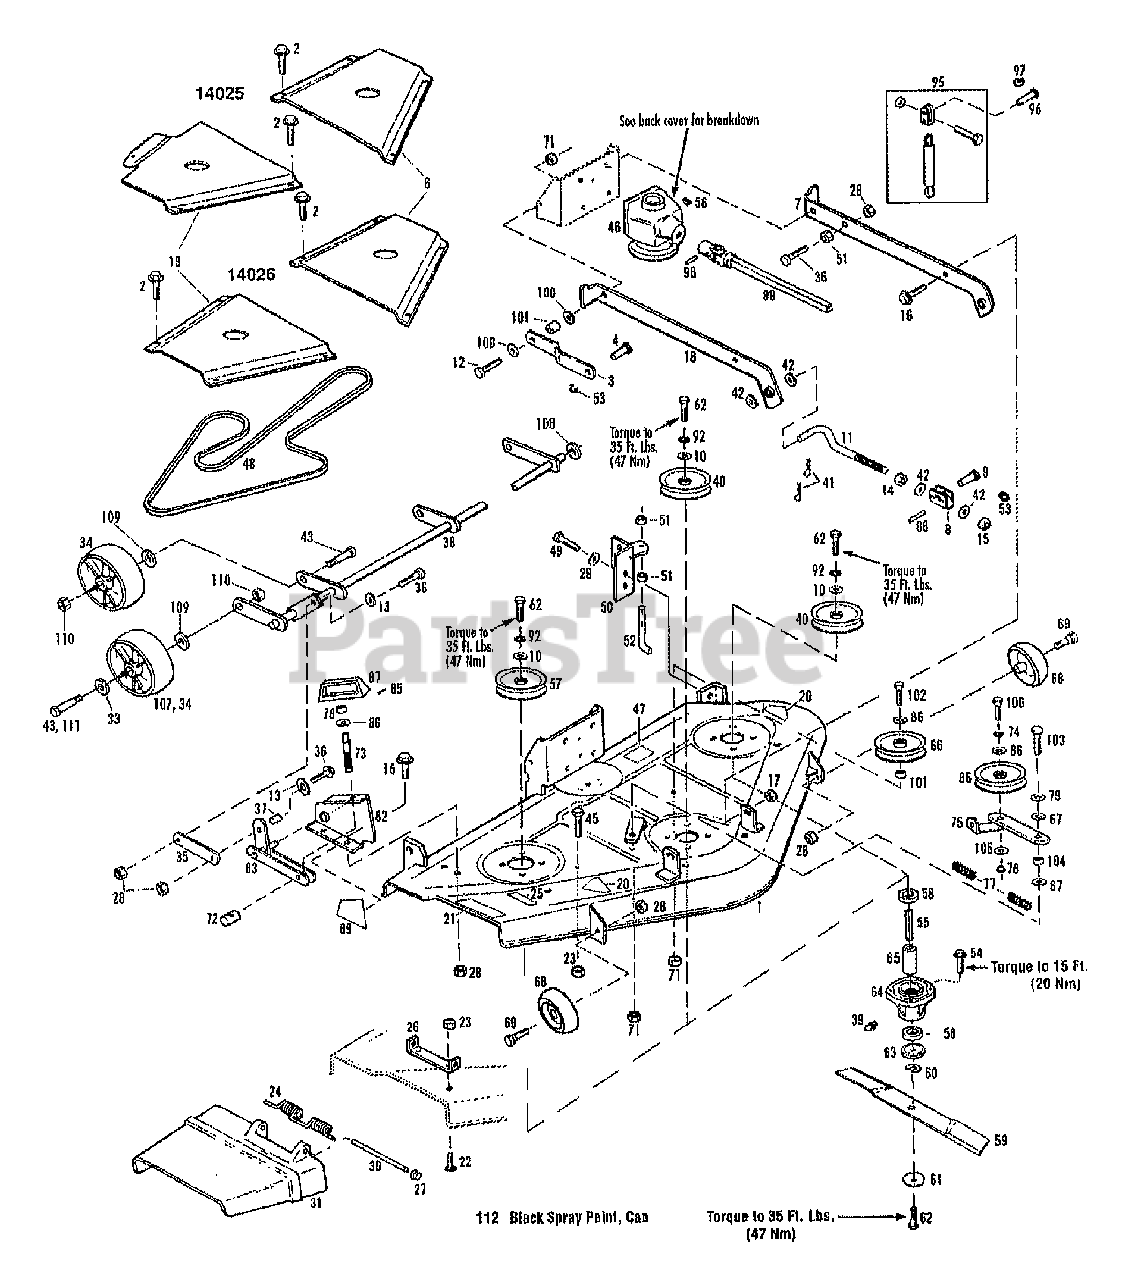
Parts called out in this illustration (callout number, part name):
1	BASE-MOWER 42" SD W/DECALS {14025}
1	BASE-MOWER 48" SD W/DECALS {14026}
2	SCR 1/4-20X.5 FL SELF TAP
3	LINK-DRAG
4	PIN-CLEVIS .625X1.44
6	COVER-BELT LH {14025}
6	COVER-BELT LH {14026}
7	SUPPORT-DECK LH
8	BRKT-HITCH
9	PIN-CLEVIS .62X2.50 ZP
10	WASHER-1.25X.5X.083 ZP
11	LINK-HITCH
12	SCR-HH 1/2-13X1.75 G5 ZP
13	WASHER-FLAT 3/8 SAE
14	NUT
15	NUT-H/LK 3/4-10
16	SCR-HFLK 3/8-16X1.00 ZP
17	NUT-HFLK 3/8-16 ZP
18	SUPPORT-DECK RH
19	COVER-BELT RH {14025}
19	COVER-BELT RH {14026}
20	DECAL-OPEI CAUTION
21	DECAL-DANGER
22	BOLT-CARR 5/16-18X.63 ZP
23	NUT-TOP/LK 5/16-18 ZP
24	SPRING-TORSION
25	DECAL-CUTTING LINE
27	NUT-PUSH 3/8 ZP
28	NUT-LOCK 3/8-16
29	WASHER-1.12X.378X.125
31	DEFLECTOR-DISCHARGE
33	WASHER-1.06X.531X.1 ZP {14025}
33	WASHER-1.305X.649X.098 ZP {14026}
34	GAUGE-WHEEL {1405}
34	GAUGE-WHEEL {14026}
35	LINK-CONNECTING {14025}
35	LINK-CONNECTING {14026}
36	SCR-HH 3/8-16X1.5 G5 ZP
37	SPACER-.625X.39X.343
38	PIVOT SHAFT ASSY
38	PIVOT SHAFT ASSY.
39	FITTING-GREASE 1/4-28X2.00
40	SHEAVE ASSY.
41	PIN-COTTER .120X1.25 ZP
42	WASHER-1.38 X.765X .06 ZP
43	SHOULDER BOLT
45	SCR-HH 5/16-18X1.25 G5ZP
46	ASSM-GEAR CASE
47	DECAL-BELT DRIVE
48	BELT {14025}
48	BELT-V {14026}
49	SCR-HH 3/8-16X1.0 G5 ZP
50	SUPPORT-SHAFT
51	NUT-HEX/JAM 3/8-16 ZP
52	BOLT-HOOK
53	RING-COTTER
54	SCR-HFLK 5/16-18X.75
55	SHAFT-SPINDLE
57	ASSM-SHEAVE DRIVE
58	BEARING-BALL
59	BLADE-LIFT {14025}
59	BLADE-LIFT {14026}
60	RING-RETAINING EXT .694 ID
61	WASHER-BELLEVILLE
62	SCR-HH 1/2-14X1.00
63	SPACER-BLADE
64	HOUSING-SPINDLE
66	PULLEY-IDLER
67	WASHER
68	WHEEL-GAGE
69	SCR-SHLDR 3/8-16
71	NUT-TOP LOCK 1/2-13 ZP
72	PIVOT-ADJUSTING SCR
73	ROD-ADJUSTING
74	WASHER-LK .5
75	ARM-IDLER {14025}
75	ARM-IDLER {14026}
76	BUTTON-WEAR
78	SPACER-HANDLE
79	WASHER-1.06X.531X.1 ZP
82	ASSM-ADJ BRKT
83	ASSM-ADJ ARM
85	PIN-ROLL .188X1.0
86	WASHER-FLAT .88X.5X.06 ZP
87	HANDLE-HEIGHT ADJ
88	PIN-DRIVE
89	DECAL-HEIGHT ADJUST
92	WASHER-LK .438 ZP
95	KIT-CHAIN
96	PIN-CLEVIS
97	RING-CIRCLE COTTER
98	PIN-DRIVE
99	ASSM-DRIVESHAFT
100	WASHER-1/2 FLAT
101	SPACER-TUBULAR
102	SCR-HH 1/2-13X2.0 G5 ZP
103	SCR-HH 1/2-13X1.5 G5 ZP
104	SLEEVE-BEARING
105	WASHER-.505X.22X.05
106	SCR-HH 1/4-20X1.25 G5 ZP
107	WHEEL-GAGE {14026}
109	WASHER-.5 DIA
111	BOLT {14026}
112	PAINT-BLACK SPRAY
